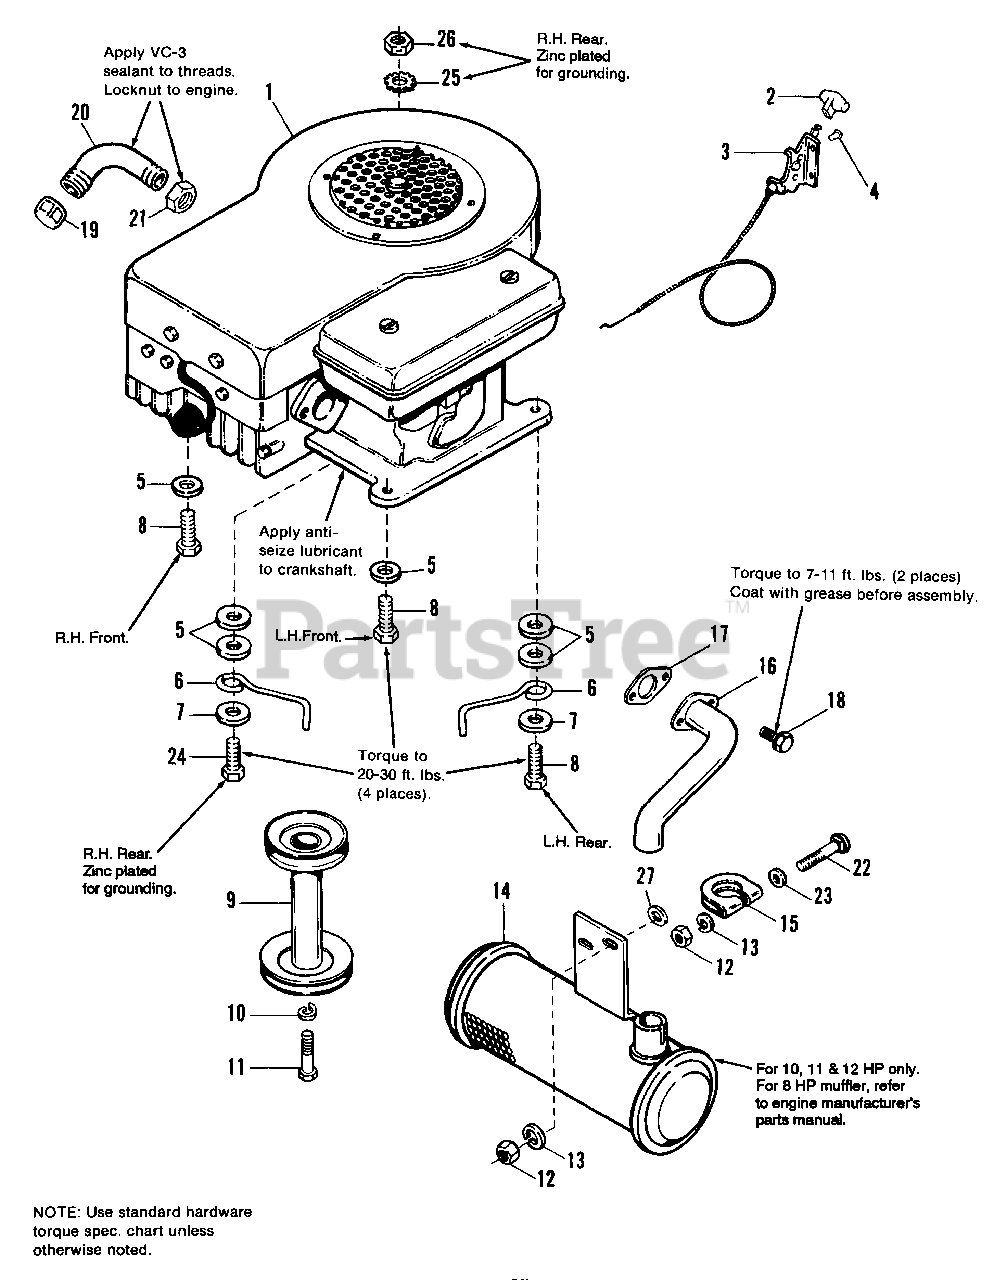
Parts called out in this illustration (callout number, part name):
2	KNOB, Throttle
3	CONTROL ASSY., Throttle (Early models with 13" cable)
3	CONTROL ASSY., Throttle (Later models with 14" cable)
4	RIVET, Pop, 1/4
5	WASHER, Plain, 3/8 (Qty. 5 on 12 HP)
7	WASHER, 13/32
8	SCREW, Taptite, 3/8-16 x 1-1/2
9	PULLEY ASSY., Engine
10	LOCKWASHER, 7/16
11	CAPSCREW, Hex, 7/16-20 x 1-1/4
12	NUT, Hex, 5/16-18 (Qty. 2 on 8 HP)
13	LOCKWASHER, 5/16 (Qty. 2 on 8 HP)
14	MUFFLER
15	CLAMP
16	PIPE, Exhaust
17	GASKET, Muffler
18	SCREW, Whizlock, 5/16-18 x 3/4
20	PIPE, Oil Drain (Incl. Ref. Nos. 19 & 21)
21	LOCKNUT
22	BOLT, Carriage 5/16-18 x 2-3/4 Gr. 5
23	WASHER
24	SCREW, Taptite, 3/8-16 x 2, Zinc Pltd.
25	LOCKWASHER, Ext., 3/8, Zinc Pltd.
26	NUT, Hex Jam Lock, 3/8-16, Zinc Pltd.
27	LOCKWASHER (1691028, 1691541 only)
